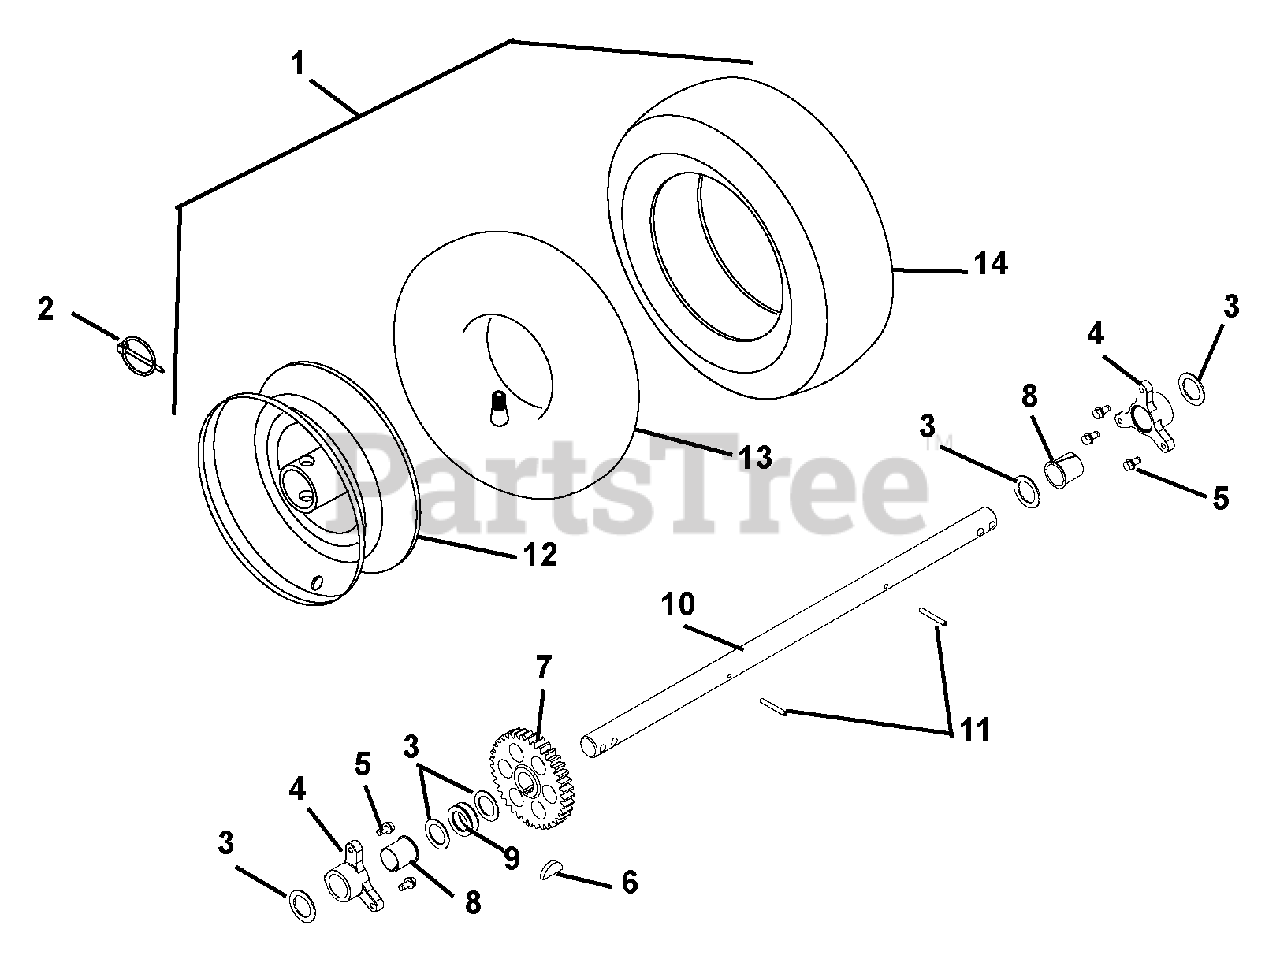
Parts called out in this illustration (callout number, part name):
1	TIRE/WHEEL, RH 15X5.00-6 PIN
1	TIRE/WHEEL, LH 15X5.00-6 PIN
2	PIN-LOK .31X2.00
3	WSHR-FL-STL 1.010X1.505X.062YZ
4	BUSHING, RAKE SHAFT 1"
5	@SCR-TAP .25-20X.50 HWH TR YWZ
6	KEY-WDRF .25X.750X.313 SAE91
7	GEAR, SPUR
8	BSHG-FLG SPLIT NYLINER 1.0" HP
9	SPACER 1.005X1.5075X.375
10	AXLE, 1.00" SOLID
11	PIN-ROLL .188X1.50
13	TUBE 15 X 5.00-6
14	TIRE, X-TRAC 15X5-6
